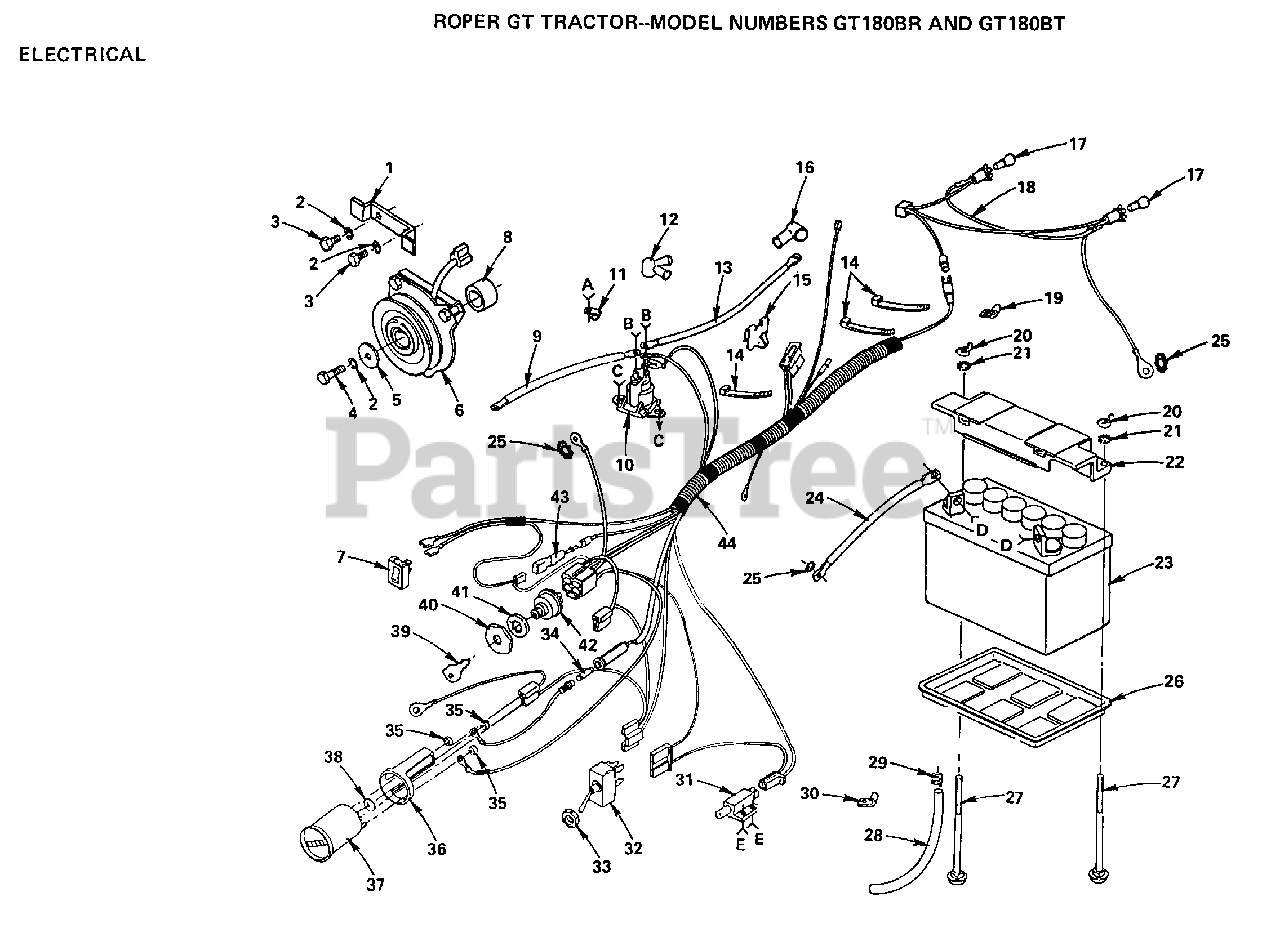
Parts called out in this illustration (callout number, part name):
1	STOP CLUTCH T
2	LOCKWASHER
3	BOLT
4	BOLT
5	WASHER GT
8	SPACER-CLUTCH GT
9	CABLE-BATTERY T
12	TERM COVER DUAL
14	WIRE TIE
15	CLIP-HARNESS
17	HEADLAMP BULB
19	CLIP GT
21	WASHER
25	LOCKWASHER
26	"TRAY T, BATTERY"
27	BOLT
30	CLIP GTV
31	SWITCH-INTER. GT
32	SWITCH.PTO.T
33	HEX NUT T
34	FUSE-30 AMP
35	"NUT,KEPS"
37	METER - HOUR, AMPS
40	CONDUIT NUT L
41	LOCKWASHER
44	HARNESS, IGNITION
